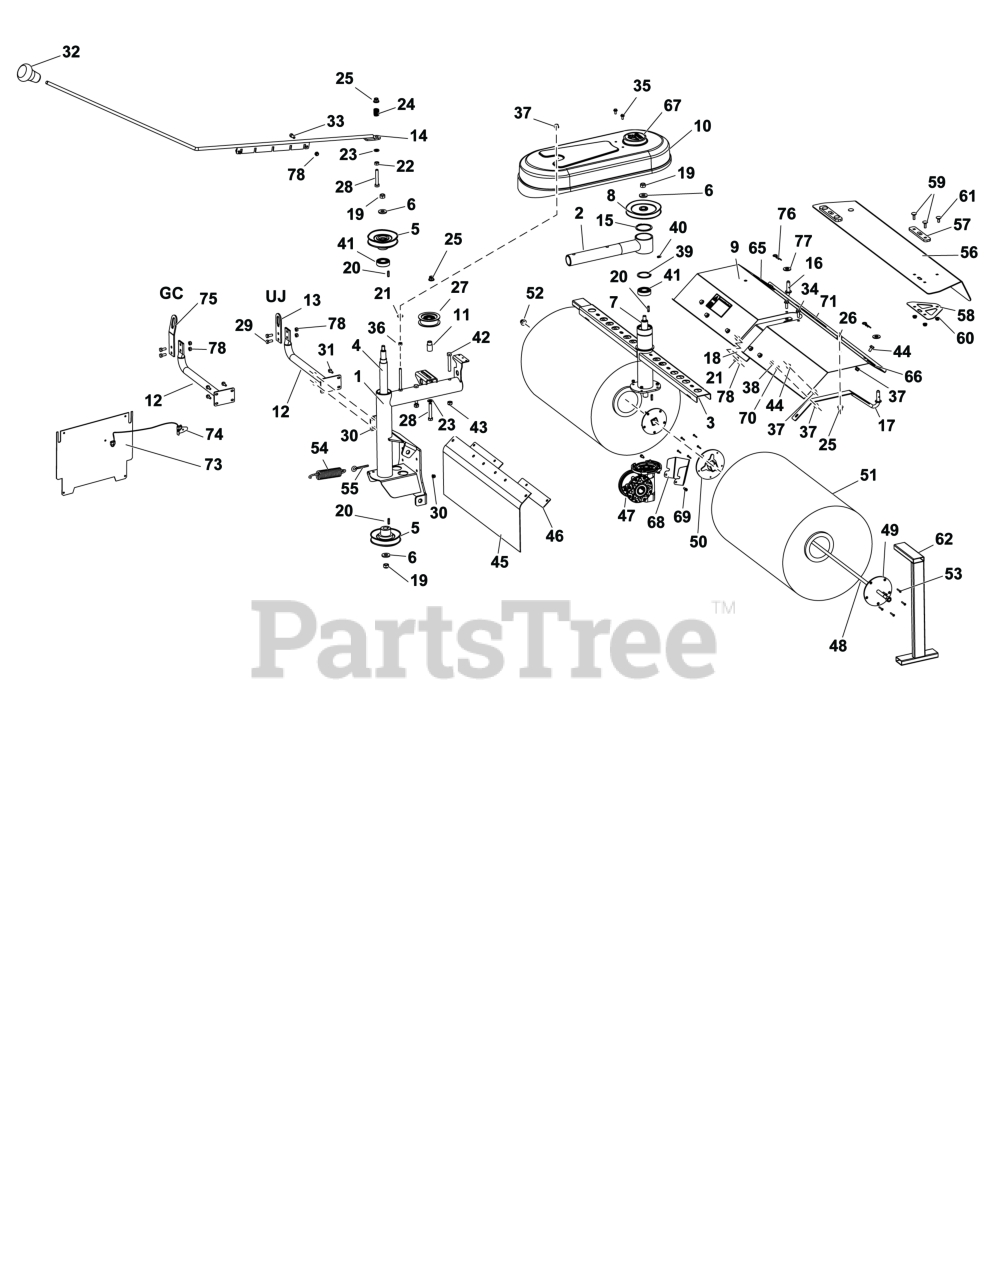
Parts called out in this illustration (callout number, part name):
13	PLATE
40	ZERK, Grease Fitting
47	TRANSMISSION
55	EYE BOLT
67	DECAL
71	DECAL
75	PLATE
